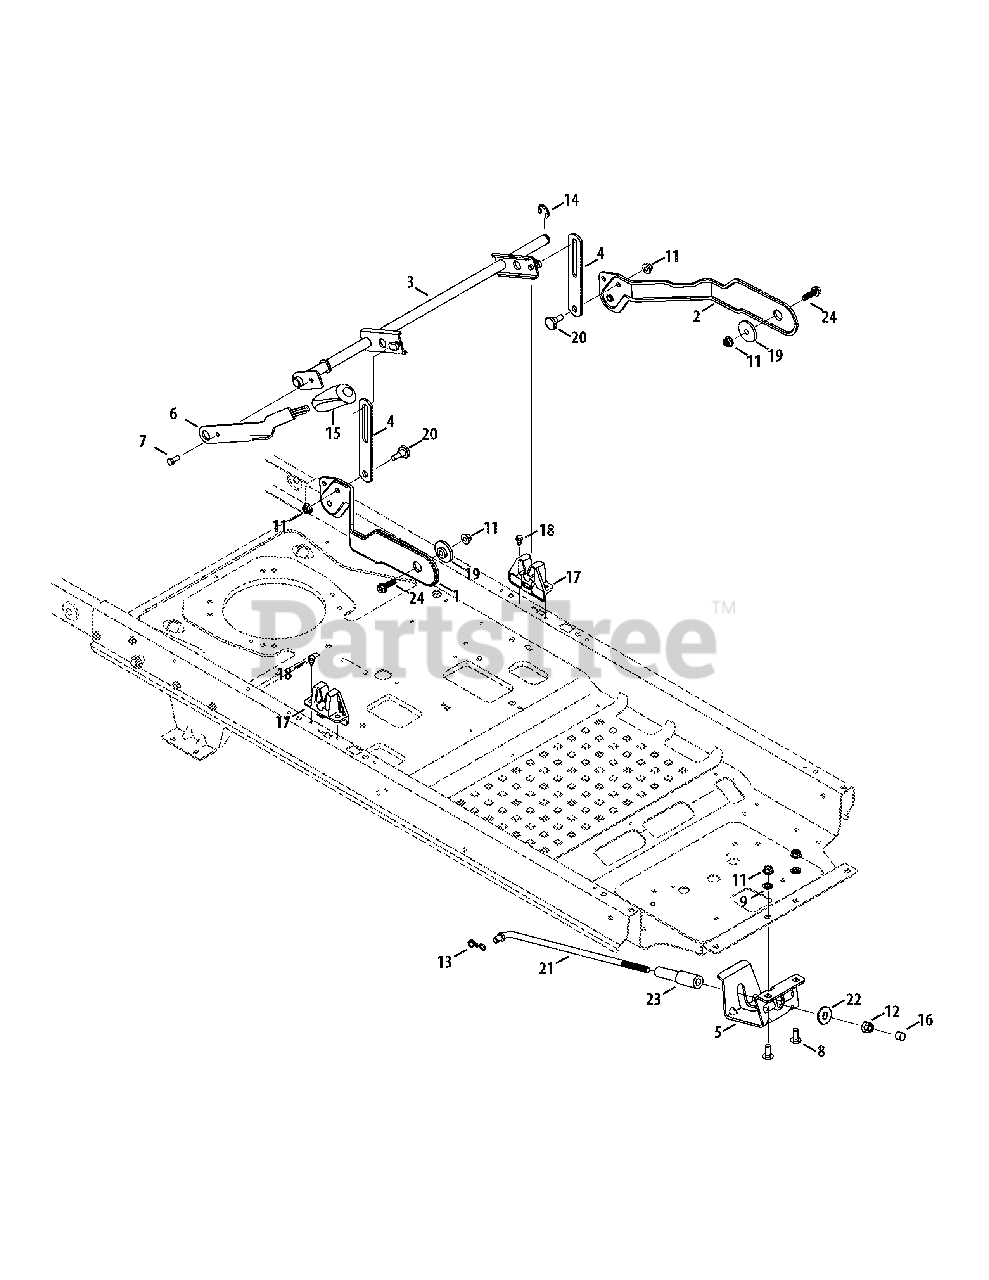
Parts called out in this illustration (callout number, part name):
1	RH Deck Lift Bracket Assembly
2	LH Deck Lift Bracket Assembly
3	Deck Lift Shaft Assembly
4	Lift Link Plate
5	Support Rod Mount Bracket
6	Deck Lift Handle
7	Hex Screw, 5/16-18 x .75
8	Carriage Bolt, 3/8-16 x 1.00
9	Push Nut, 3/8
10	Flange Lock Nut, 5/16-18
11	Flange Lock Nut, 3/8-16
12	Hex Nut, 1/2-13
13	Cotter Pin
14	E-Ring, .750
16	End Cap
17	Deck Lift Bracket
18	Shoulder Screw, 1/4-20 x .50
19	Anti-Rotate Shoulder Spacer
20	Shoulder Screw, .500 x .434
21	Front Deck Lift Rod
22	Deck Lift Pivot Cup
23	Nylon Sleeve, .55 x 4.50
24	Hex Washer Screw, 3/8-16 x 1.000
